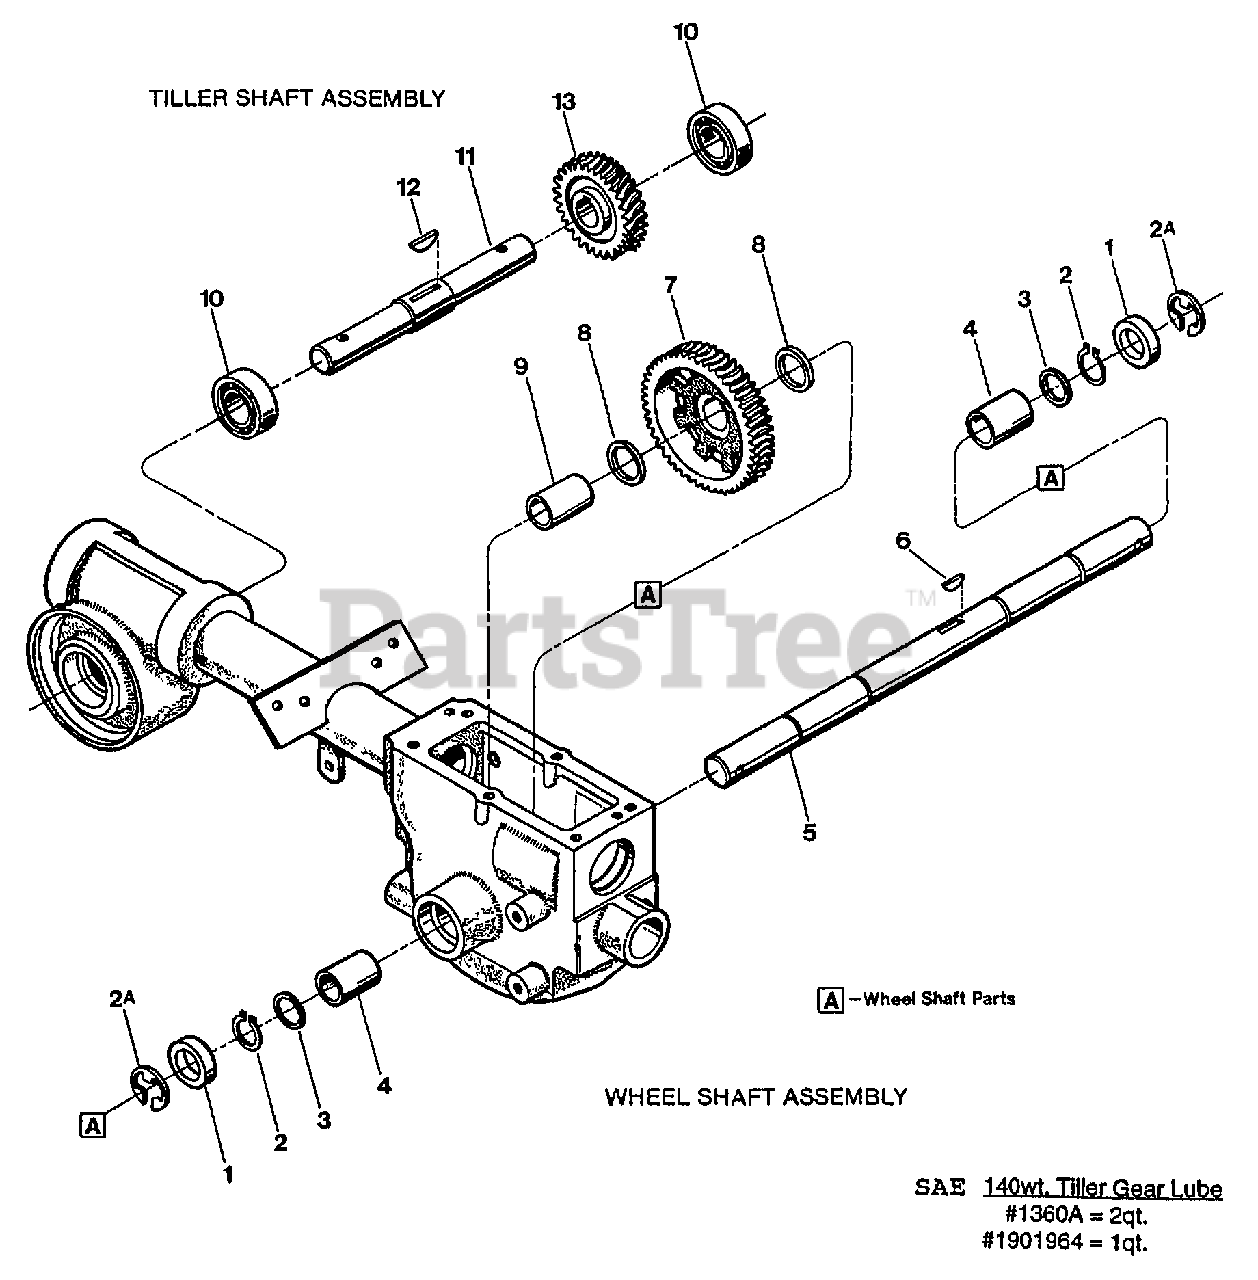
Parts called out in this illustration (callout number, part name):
1	SEAL-OIL WHEELSHAFT
2	RING-HEAVY EXT .906 ID
2A	RING-RETAINING 5133-989
3	SHIM-1.375X1.015X.062
3	SHIM-1.375X1.015X.03
3	SHIM-1.375X1.015X.015
3	SHIM-1.375X1.015X.01
4	BUSHING-1.25X1.005X1.5
5	ASSM-WHEELSHAFT W/KEY
6	KEY-HI PRO .25X.938
7	GEAR-WHEEL DRIVE (WORM GEAR), CAST IRON
7	GEAR-WHEEL DRIVE MACH
8	SHIM-1.234X1.015X.01
9	SPACER-WHEEL SHAFT
10	BEARING-BALL
11	SHAFT-W/KEY (TILLER)
12	KEY-WOODRUFF .25X1.12
13	GEAR-TILLER MACH
